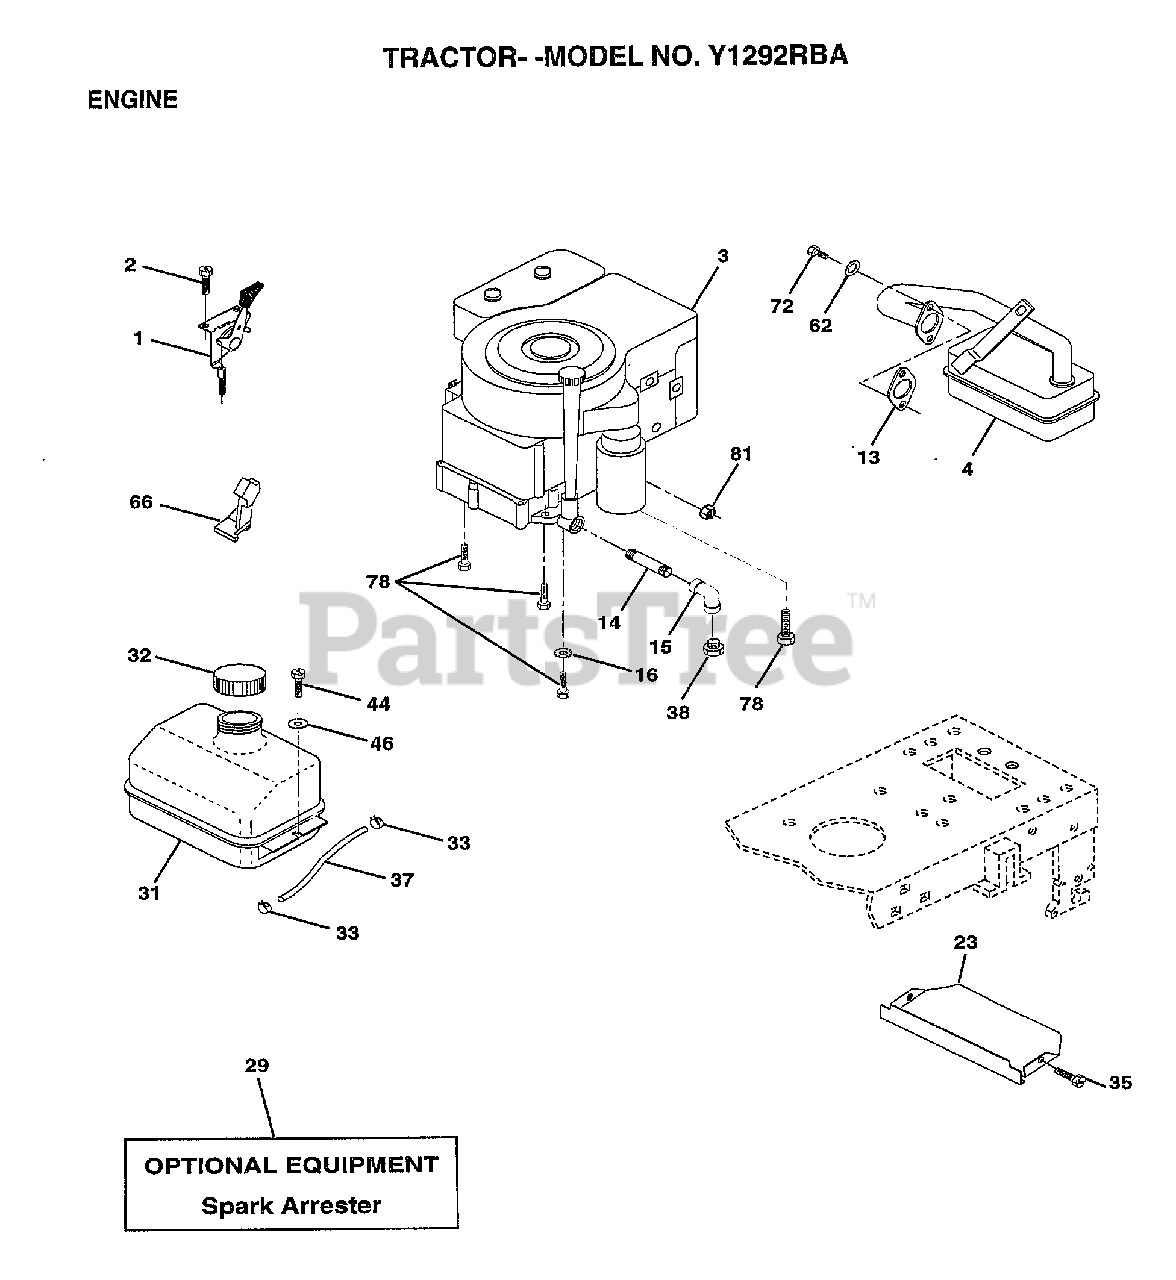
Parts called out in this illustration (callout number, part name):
1	CONTROL.THTL.23.5
2	SCREW LT
4	MUFFLER
14	PIPE NIPPLE
15	ELBOW
16	LOCKWASHER
23	SHIELD.BRN/DBR.GD
31	TANK.FUEL.LT.
32	CAP ASM FUEL
33	HOSE CLAMP
35	SCREW
37	LINE FUEL
44	SCREW HEX CRT
46	WASHER
62	LOCKWASHER
66	"STOP,DASH THROTT"
72	SCREW
78	SCREW
81	NUT
